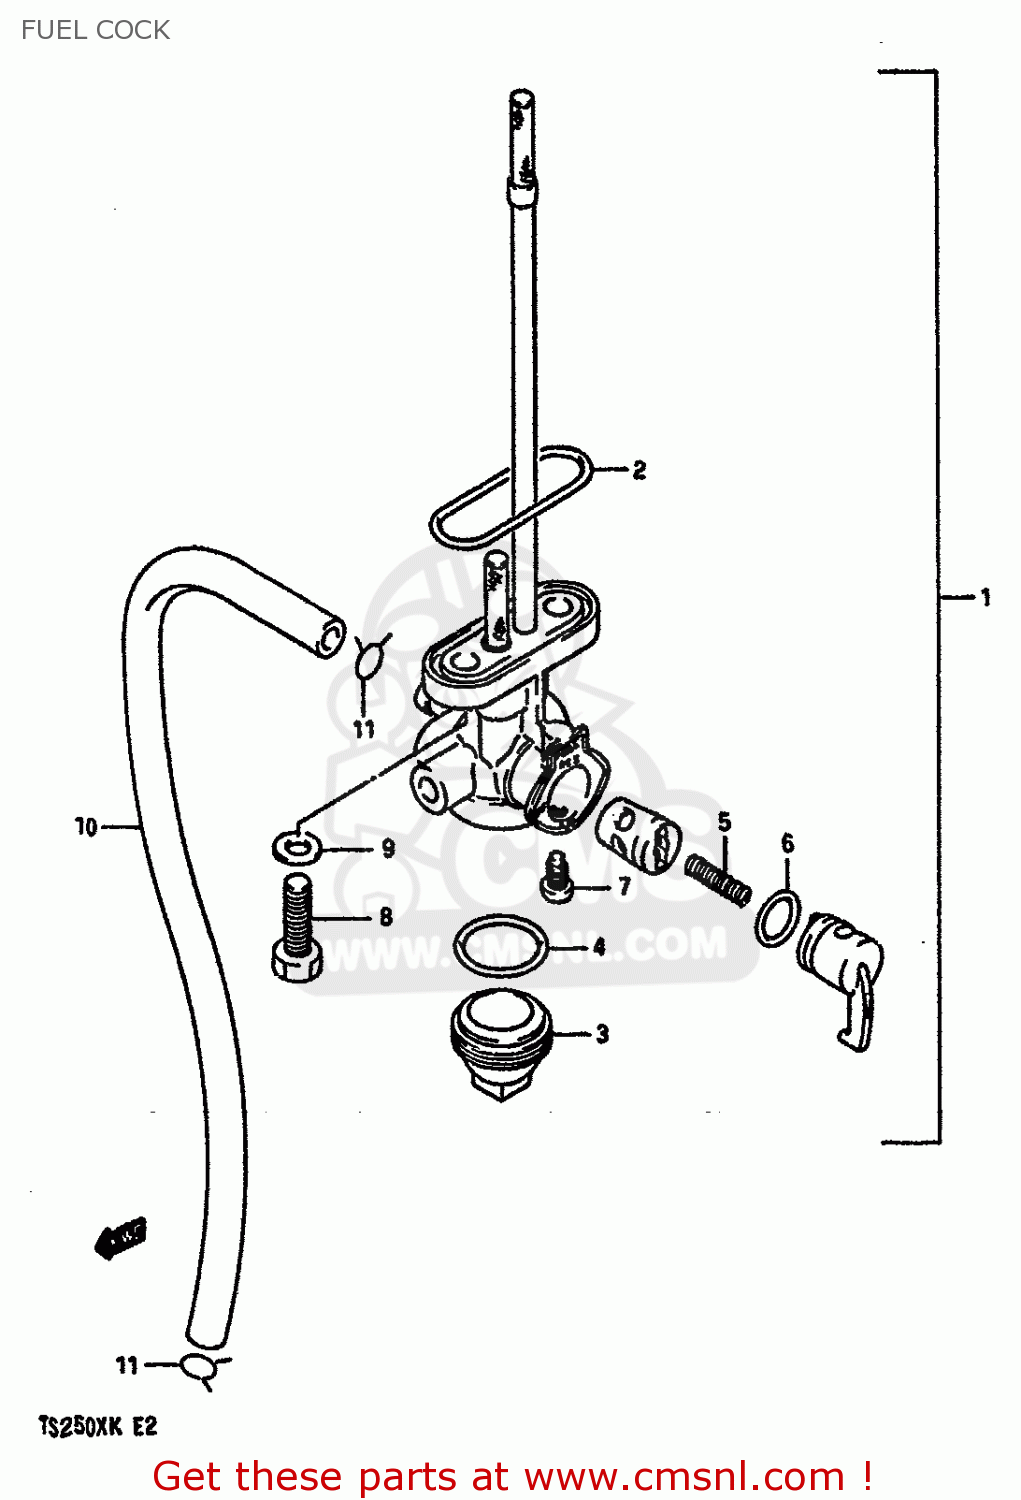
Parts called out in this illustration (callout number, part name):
1	COCK ASSY,FUEL
2	O RING,FUEL COCK
3	CUP,STRAINER
4	GASKET,FILTER (NAS)
5	SPRING
6	O-RING
7	SCREW
8	BOLT(6X20)
9	GASKET
10	HOSE
11	CLIP
